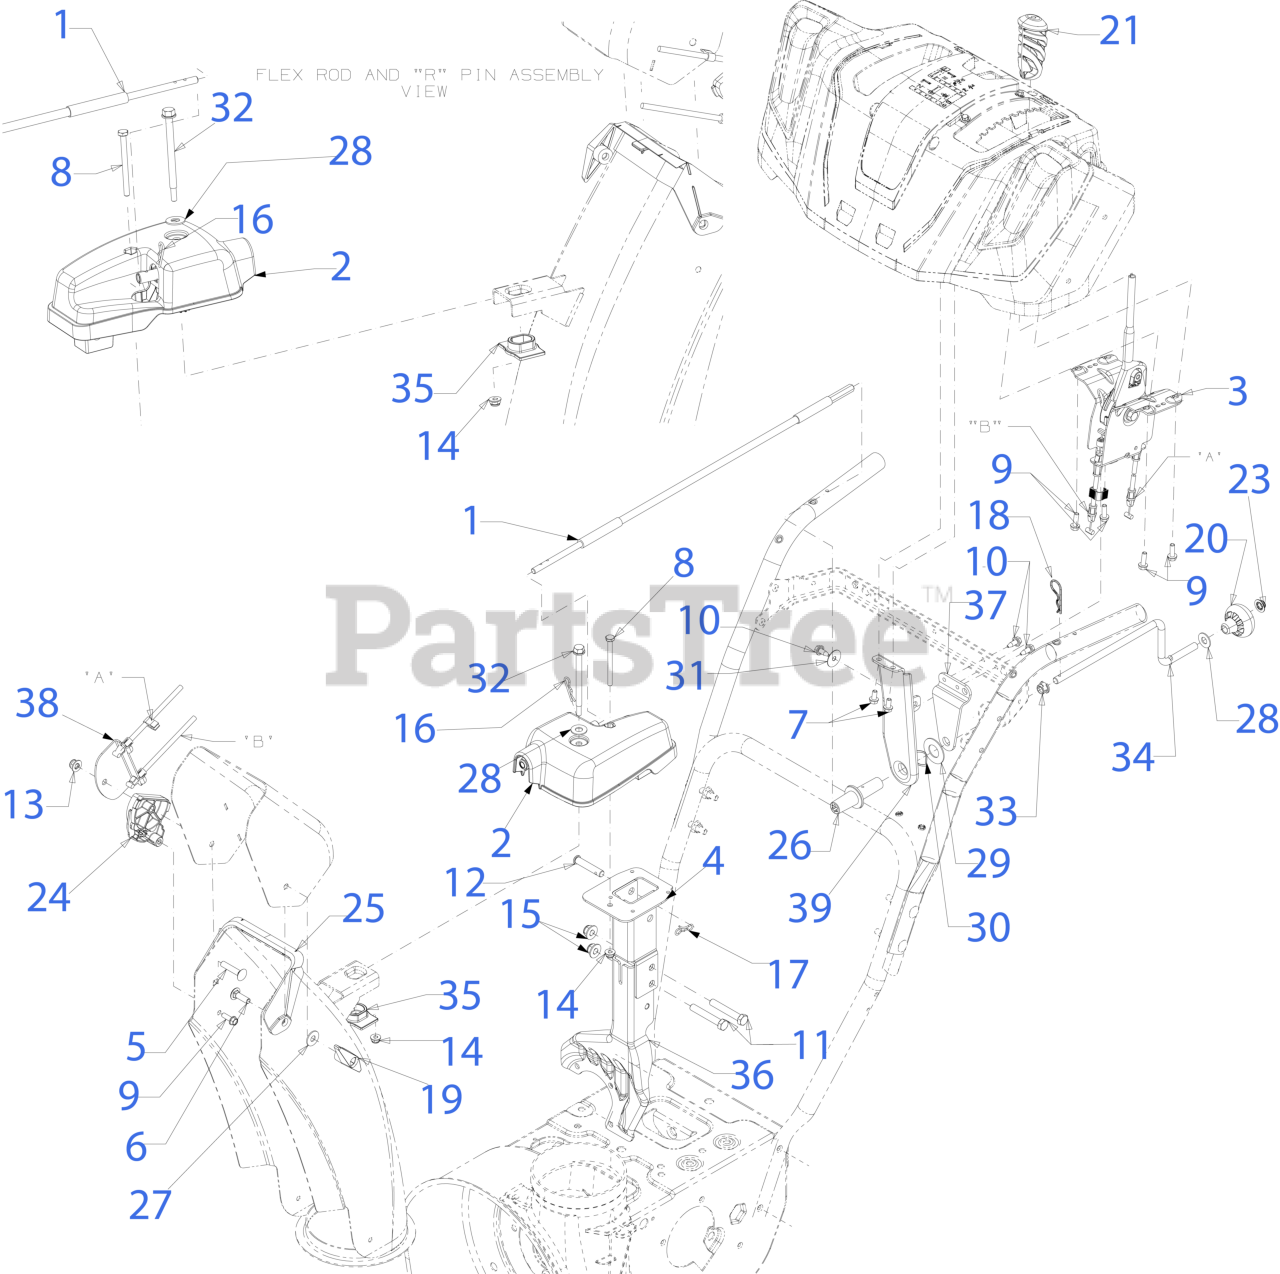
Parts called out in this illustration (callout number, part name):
1	CHUTE CONTROL
2	2-WAY CHUTE ROTATE GEARBOX
3	2-WAY STEEL CHUTE CONTROL ASSEMBLY
4	EXTENSION CHUTE MAST
5	CARRIAGE BOLT 5/16-18 x 1.50
6	CARRIAGE BOLT 5/16-18 x 1.00
7	HEX SCREW 1/4-15 x .50
8	SCREW 1/4-20 x 3.0 GR5
9	SCREW 1/4-15 x .750
10	SCREW 1/4-20X.625
11	SCREW 3/8-16 x 2.25 GR5
12	CLEVIS PIN 3/8 x 1.87
13	FLANGE LOCK NUT 5/16-18
14	FLANGE LOCK NUT
16	INTERNAL COTTER PIN
17	BOW TIE COTTER PIN 1/4-5/16
18	INTERNAL COTTER PIN
19	WING KNOB NUT
20	SHIFT KNOB
21	PTO HANDLE GRIP .355 ID
24	CHUTE TILT GUIDE
25	UPPER CHUTE ADAPTER
26	CHUTE ROD COUPLER
27	FLAT WASHER
28	FLAT WASHER
29	FLAT WASHER
30	WAVE WASHER .785X1.00X.012
31	FLAT WASHER
32	SHOULDER SCREW
33	BUSHING .380 ID
34	CHUTE CRANK (POWDER BLACK)
35	HELICAL GEAR CHUTE ADAPTER
37	ROD SUPPORT BRACKET
